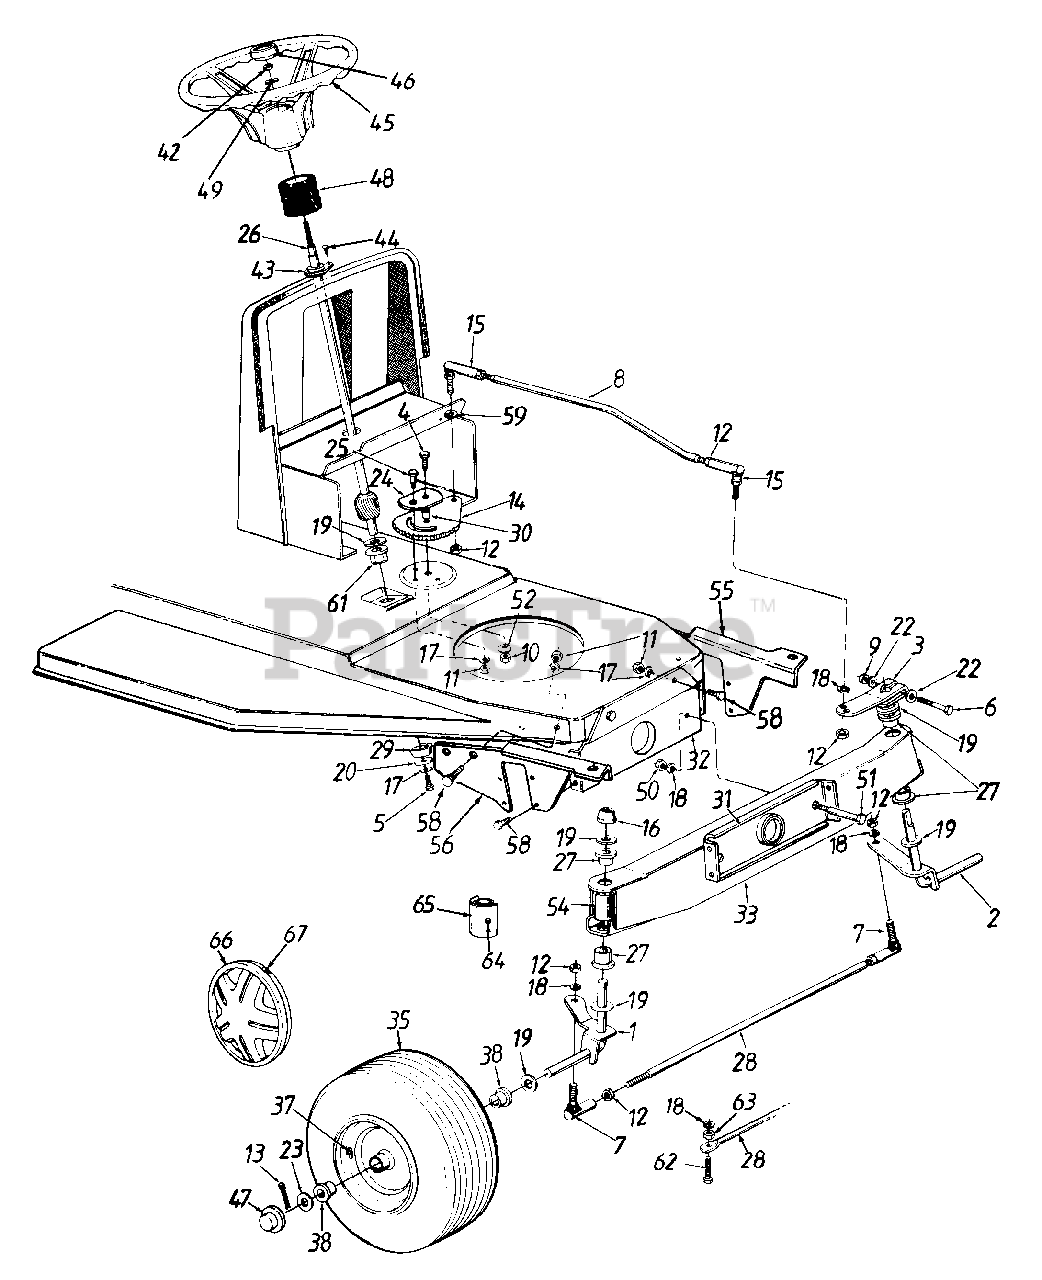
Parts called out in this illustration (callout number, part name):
1	Front Axle Ass'y. - R.H.
2	Front Axle Ass'y. - L.H.
3	Steering Arm
4	Hex Bolt 3/8-24 x 1" Lg.
5	Hex Bolt 5/16-18 x .62" (Spec.)
6	Hex Bolt 5/16-24 x 2" Lg.
7	Ball Joint 3/8-24 Thd.
8	Steering Drag Link
9	Hex L-Nut 5/16-24 Thd.
10	Hex Nut 3/8-24 Thd.
11	Hex Nut 5/16-18 Thd.
12	Hex Jam Nut, 3/8-24 Thd.
13	Cotter Pin 1/8 Dia.
14	Steering Gear Segment
15	Drag Link Ball Joint 3/8-24 Thd.
16	Push Cap
17	L-Wash. 5/16" I.D.
18	L-Wash. 3/8" I.D.
19	Fl-Wash. .64" I.D. x 1.24"
20	Fl-Wash. .340" I.D. x 1.125"
22	Spr. Wash. .32" I.D. x .62"
23	Fl-Wash. .635" I.D. x 1.585"
24	Retainer Plate
25	Shld. Bolt .437" Dia. x .350"
26	Steering Shaft
27	Hex Flange Brg. .632" I.D.
28	Tie Rod (Adjustable)
29	Spacer .985" I.D.
30	Spacer .380" I.D.
37	Air Valve
38	Bearing - Plastic
42	Hex L-Nut 5/16-24 Thd.
43	Steering Column Brg.
44	Cr-Sunk Scr. #10 x 5/8" Lg.
45	Steering Wheel (3 Spoke)
46	Steering Wheel Cap (Round)
47	Hub Cap
48	Bellow Steering Column (Style 2)
49	Bell-Wash. .345" I.D. x .88"
50	Hex Nut 3/8-16 Thd.
51	Shld. Bolt 1/2" Dia. x 2.04"
52	Bell-Wash. .39" x 1.38" O.D.
54	Plastic Tube
59	L-Wash. 3/8" I.D. (H.D.)
61	Hex Flange Brg. .634" Dia.
62	Hex Bolt 3/8-24 x 1.5" Lg.
63	Hex Jam Nut 3/8-24 Thd.
64	Grease Fitting
65	Pivot Bar End Cap
66	Spring Clip
67	Hub Cap (Beige)
